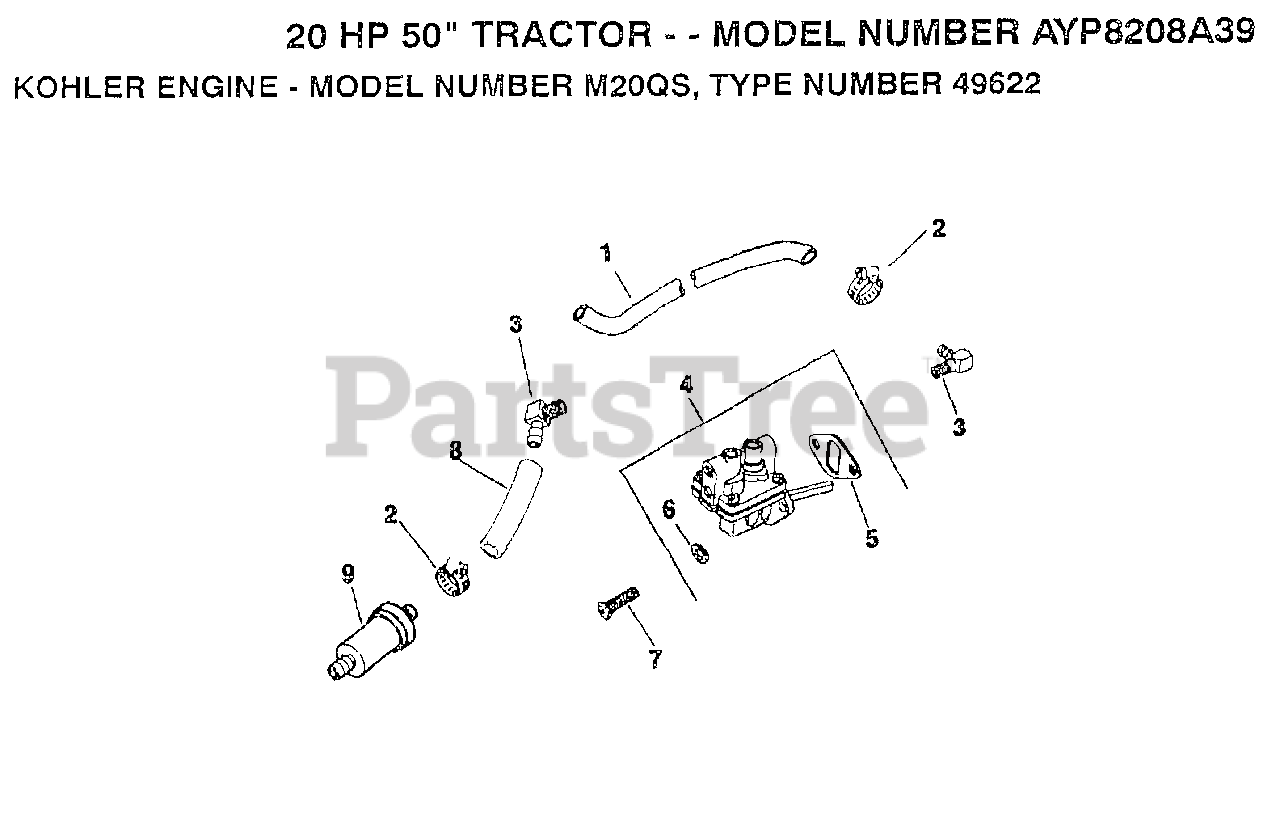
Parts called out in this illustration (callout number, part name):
2	CLAMP, HOSE
3	CONNECTOR, HOSE
4	PUMP, FUEL ASSEMBLY
5	GASKET, FUEL PUMP
6	WASHER, PLAIN 1/4
9	FILTER, FUEL
